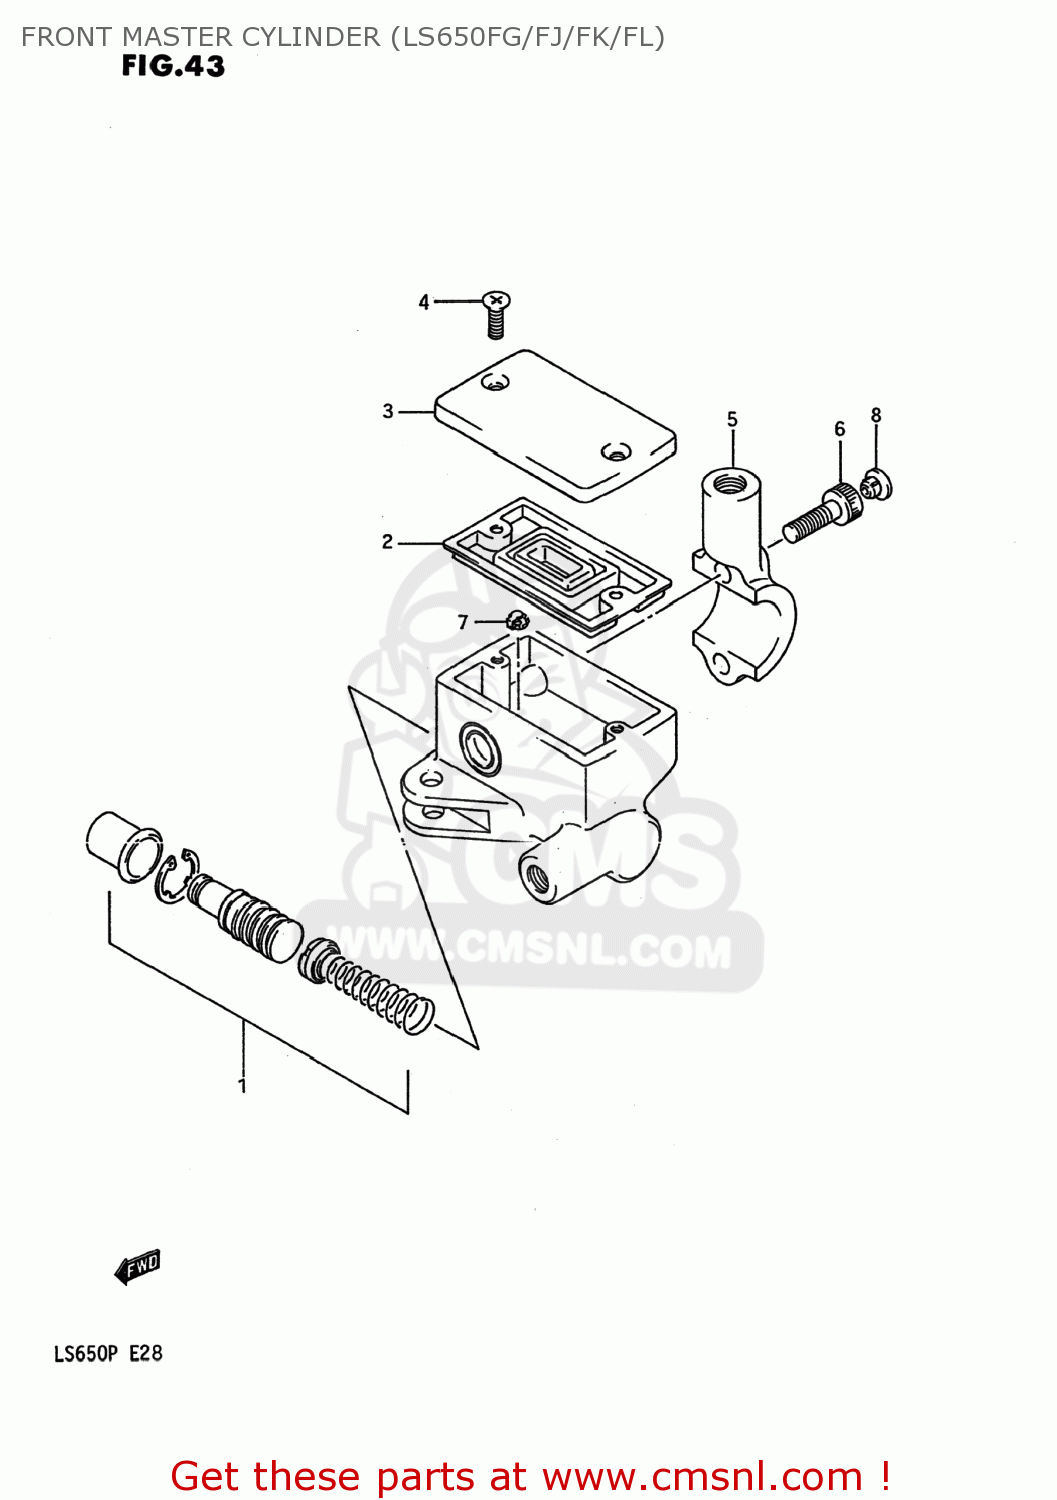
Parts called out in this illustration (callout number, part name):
1	CUP SET,MASTER CYLINDER
2	3-1
3	CAP
4	SCREW,RESERVOIR CAP
5	HOLDER
6	BOLT ,6X20
7	PROTECTOR
8	CAP(OD:10)
